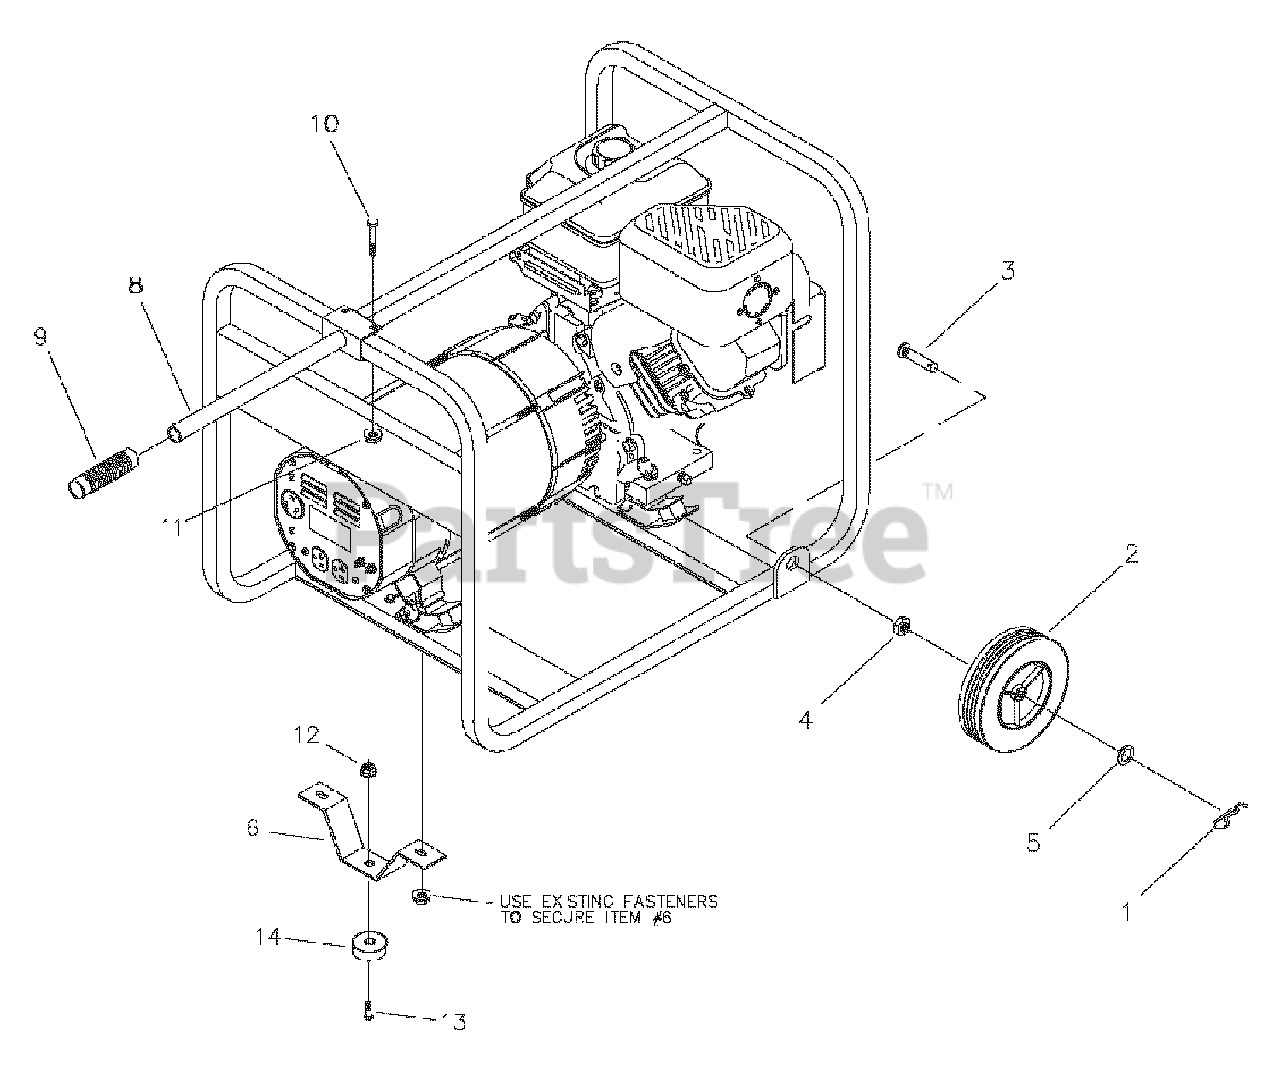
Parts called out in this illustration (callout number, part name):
1	PIN, Retaining
2	WHEEL
3	STUD, Axle
4	JAM NUT, Lock
6	LEG, Mounting
8	HANDLE, Lifting (Includes Item 9)
9	GRIP, Handle
11	NUT, Lock
12	NUT, Lock
14	MOUNT, Rubber Donut
